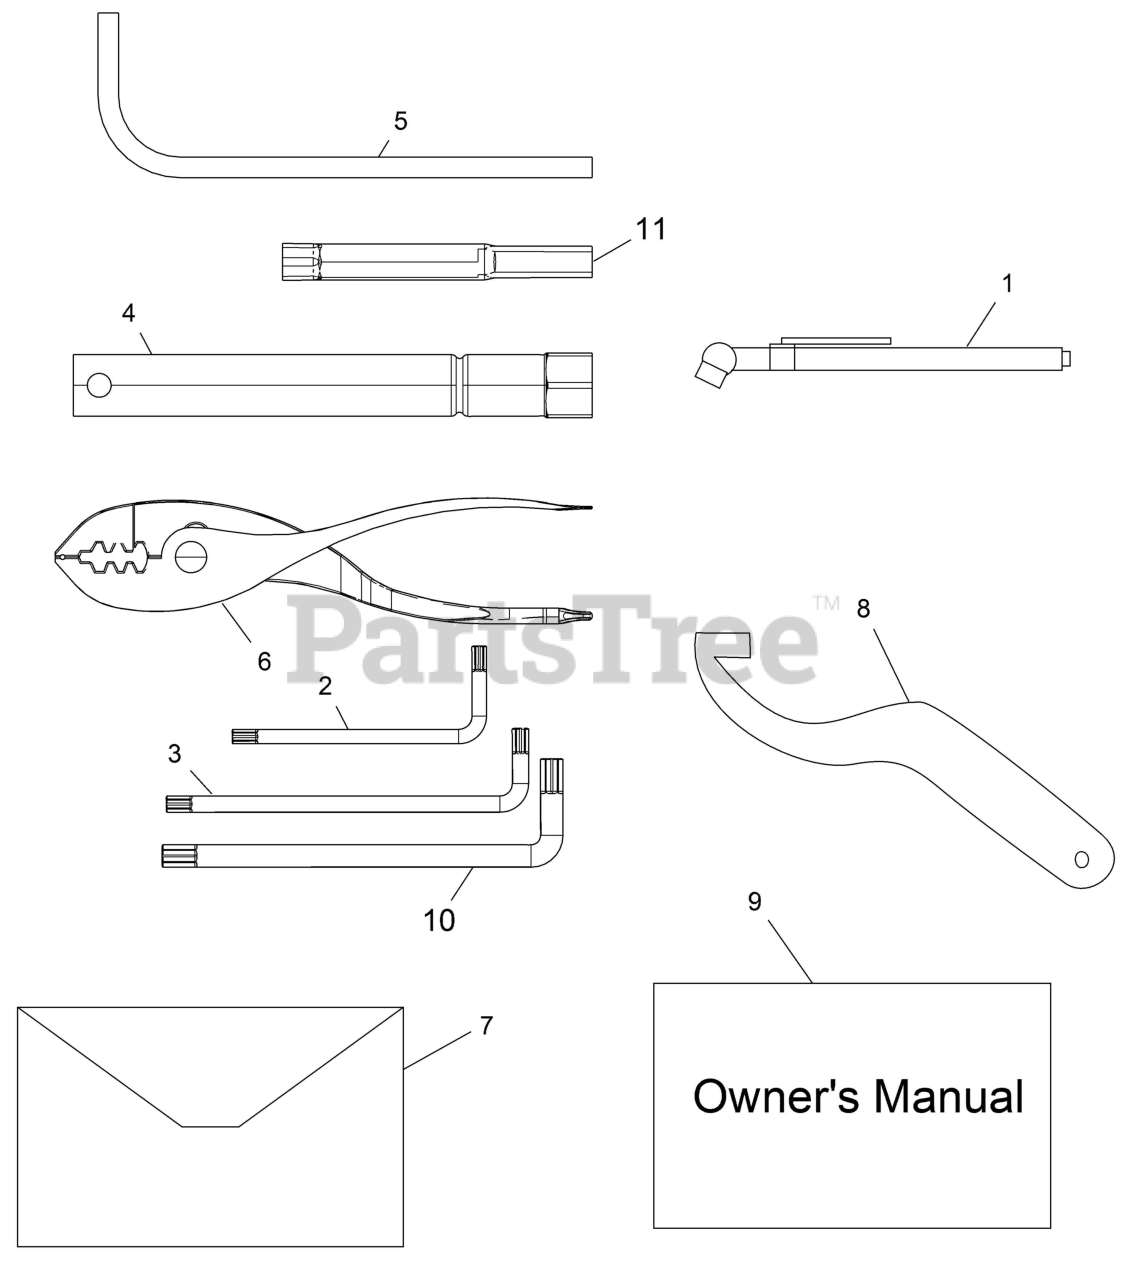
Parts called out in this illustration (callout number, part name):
1	GAUGE-TIRE PRESSURE,30 PSI
2	WRENCH-TORX,T-25
4	SOCKET, SPARK PLUG
5	HANDLE, SPARK PLUG
6	PLIERS-COMBO, #2 ASSEMBLY
7	POUCH,TOOLKIT,9"
8	WRENCH-SPANNER, CAM
9	MAN,OWNERS,19 ARIENS 570 CREW
10	WRENCH-TORX,T-40
